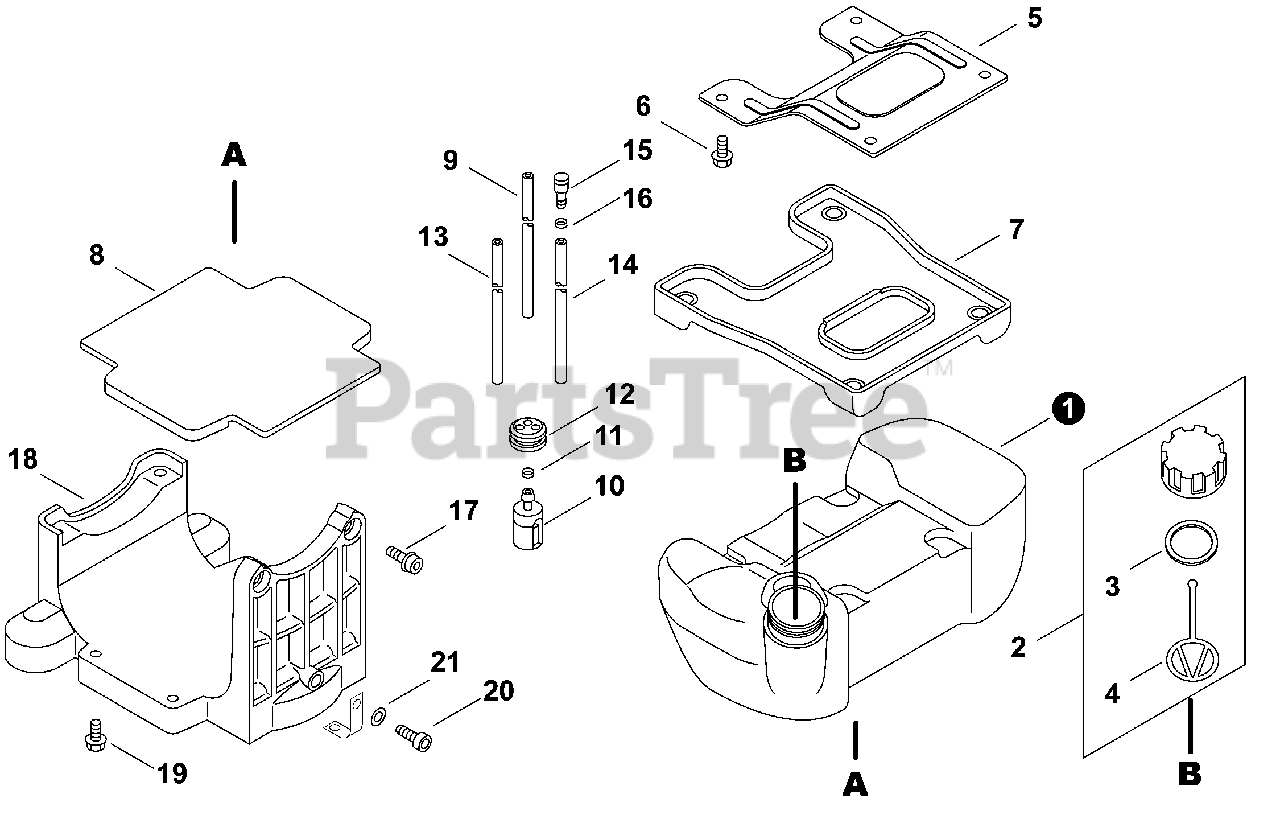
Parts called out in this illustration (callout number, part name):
1	TANK, FUEL
2	CAP ASSY, FUEL
3	GASKET, FUEL CAP
4	CONNECTOR, CAP L= 100mm
5	BRACKET, FUEL TANK
6	BOLT 5×12
7	CUSHION, UPPER
8	CUSHION, FUEL TANK
9	PIPE, FUEL 3×6×230
10	FILTER, FUEL
11	CLIP 6.5MM
12	GROMMET, FUEL
13	PIPE, FUEL 3×6×120 BLACK
14	PIPE, FUEL 3×6×120
15	VENT ASSY
16	CLIP 6.5MM
17	BOLT 5×25
18	PLATE, MOUNTING
19	BOLT 5×20
20	SCREW TAPPING 5×16
21	WASHER, FLAT 5.5×10×0.8
